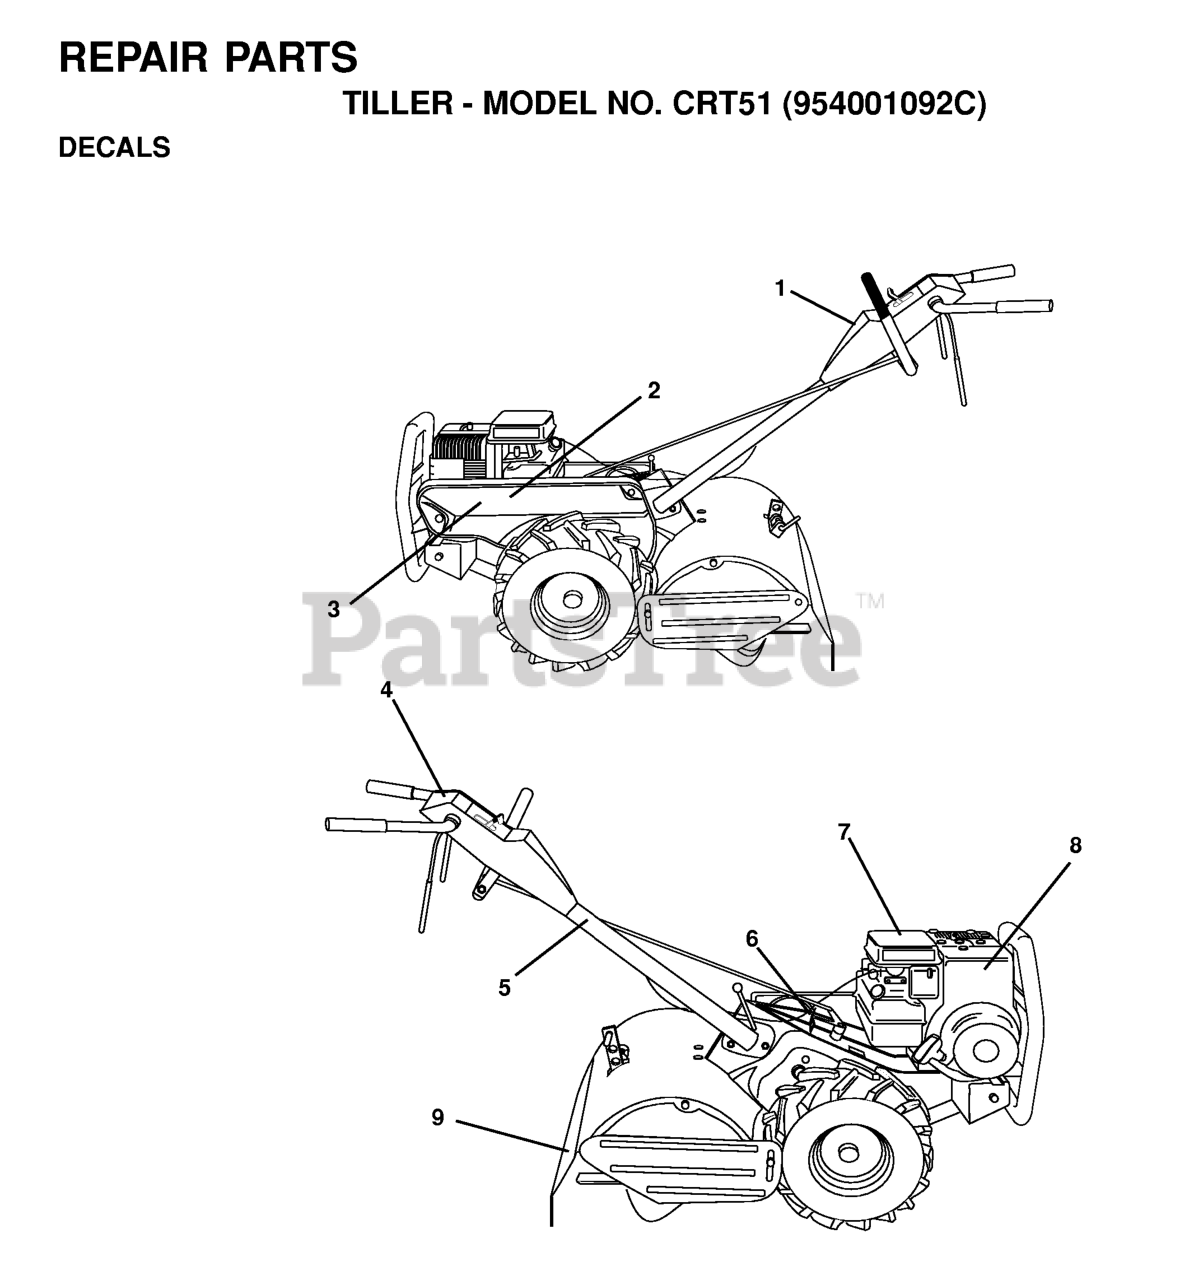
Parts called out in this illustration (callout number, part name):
1	DECAL, LOGO
2	NAMEPLATE HUSQVARNA
4	DECAL INST CONTROL PANEL
5	DECAL TI (2 2)
6	DECAL TI NLA
8	DECAL, B & S ENGINE
9	DECAL TI
